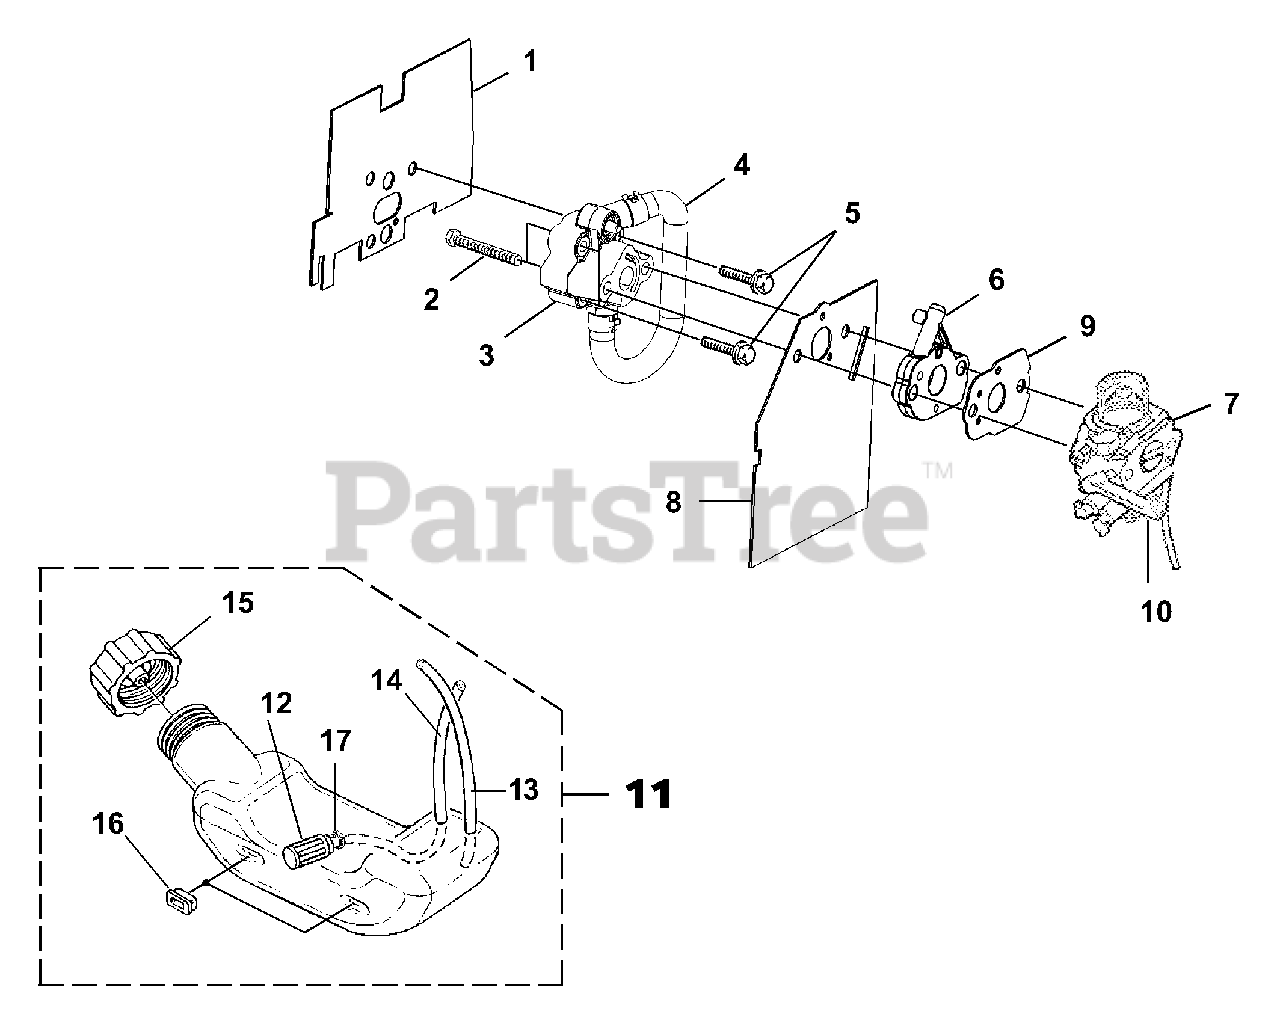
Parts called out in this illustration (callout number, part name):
1	GASKET-Heat Dam to Cylinder
2	SCREW-Shoulder
3	HEAT DAM Complete
4	TUBE-Tuned
5	SCREW-Sems (10-24 x 1")
7	CARBURETOR KIT (Yard Sweeper)
7	CARBURETOR KIT (Back Packer)
8	GASKET-Adaptor to Heat Dam
9	GASKET-Adaptor to Carburetor
10	LEVER-Choke
11	FUEL TANK ASSY.
12	FILTER-Fuel
13	TUBING-Rubber (6")
14	TUBING-Rubber (6 3/4")
15	FUEL CAP
16	BUMPER-Rubber
17	CLAMP
